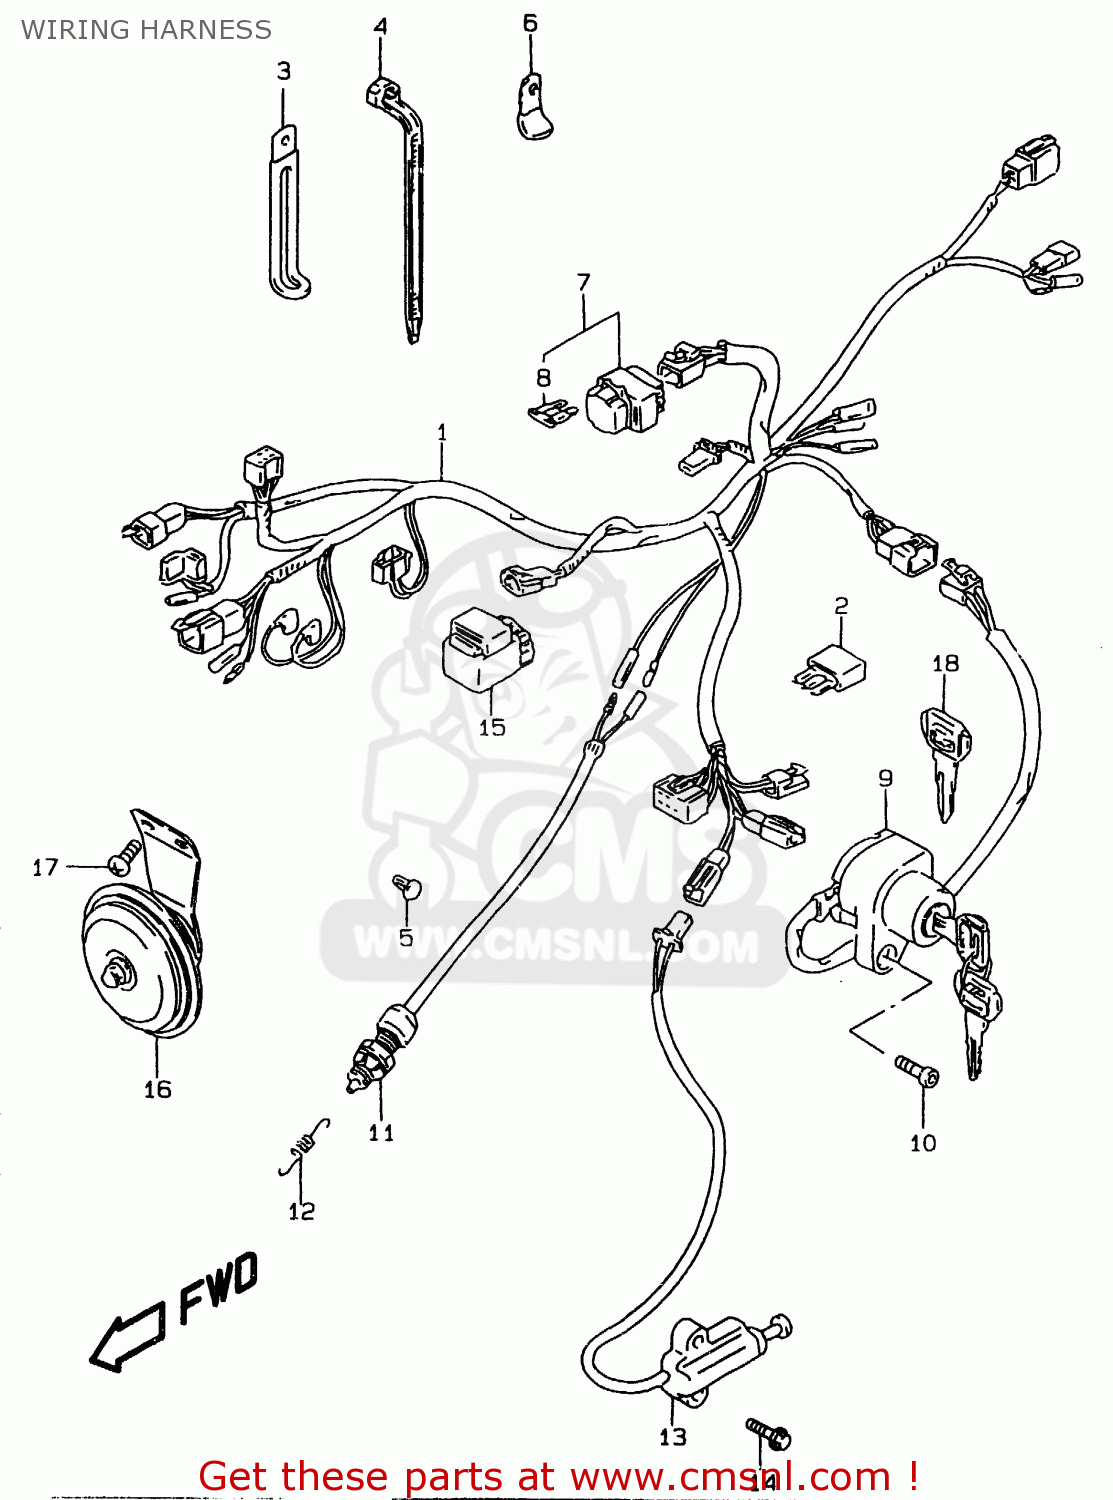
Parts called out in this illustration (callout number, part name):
1	HARNESS,WIRING
2	DIODE(STANLEY DE8804)
3	CLAMP(L:65)
4	CLAMP(L:125)
5	CLIP(BLACK)
6	CLAMP
7	BOX ASSY,FUSE
8	FUSE(20A)
9	SWITCH ASSY,IGNITION
10	BOLT
11	SWITCH ASSY,STOP LAMP
12	SPRING
13	SWITCH ASSY,SIDE STAND WARNING
14	BOLT
15	RELAY ASSY
16	HORN ASSY
17	SCREW 6X12
18	KEY,BLANK(TYPE:C)
